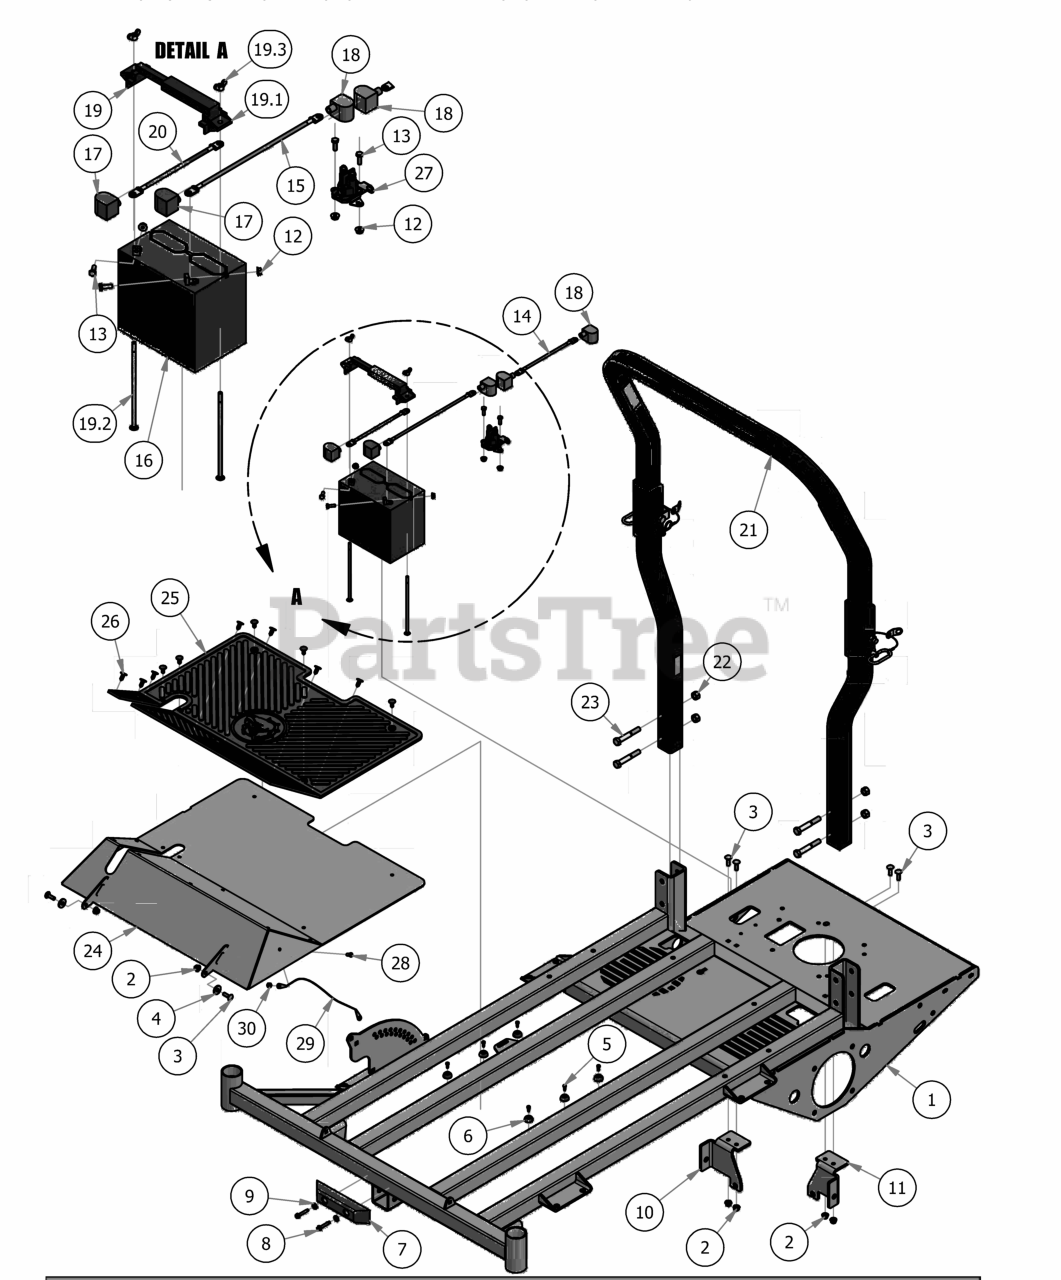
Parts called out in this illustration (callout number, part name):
1	2017 Standard/Extreme Outlaw Frame
2	5/16" Nylock Flange Nut Zinc
3	5/16" x 1" Carriage Bolt
4	.360 ID Plastic Washer
5	#10 x 1/2" Self Tapping Screw
6	Button Bumper
7	8" Rubber Bumper
8	1/4" x 1 1/2" Self Tapping Screw
9	1/4" Flat Washer
10	Outlaw Brake Cable Mount Bracket (Right)
11	Outlaw Brake Cable Mounting Bracket (left)
12	1/4-20 Hex Flange Nuts Zinc w/Serrations
13	1/4-20 x 3/4 GR 5 Hex Bolts Zinc
14	Red Battery Cable Alternator to Starter Cable (Kohler Engine Only)
15	12 in red battery cable
17	Black Boot For Ground Cable
19	Hold Down Assembly
19.1	Battery Hold Down
19.2	1/4"-20 x 8" Carriage Bolt
19.3	1/4" Wing Nut
20	Ground Cable
21	2015 Outlaw 2x2 Folding ROPS
22	1/2" Center Lock Nut
23	1/2-13 X 3.25 Hex Bolt - Grade 5
24	2016 Outlaw Floor Panel
25	Outlaw Floor Mat
26	Ratchet Fastener
27	Solenoid (Kohler Engine Only)
28	1/4" x 5/8" BS C/S 18-8 SS
29	Floor board Cable W/ Swivel Ends
30	1/4" Hex Nut
